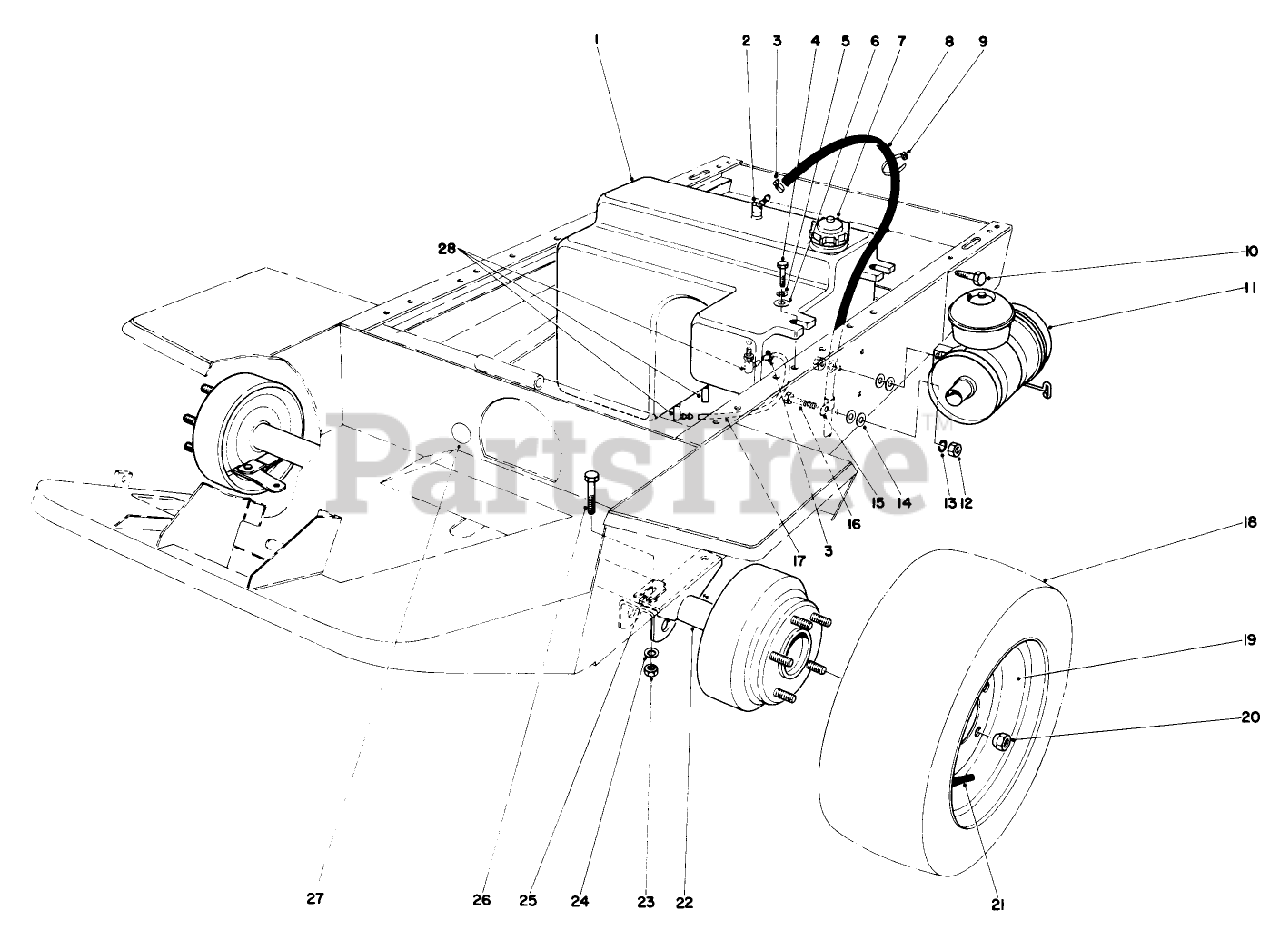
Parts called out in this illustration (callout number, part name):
1	GAS TANK
2	ELBOW
3	CLAMP-HOSE
4	SCREW-HH
5	WASHER-LOCK
6	Flatwasher
7	Gas Cap
8	GAS TANK VENT HOSE
9	Strap
10	SCREW-HH
11	AIR CLEANER ASM SERV
12	NUT-HEX
13	Lockwasher
14	WASHER-PLAIN
15	Clamp
16	SCREW-HH
17	HOSE-FUEL
18	20 X 8.00 - 10 TIRE
19	WHEEL ASM
20	NUT-WHEEL
21	VALVE STEM AND CAP ASM
23	NUT-HEX
24	WASHER-LOCK
25	SHIM-AXLE
26	SCREW-HH
27	OIL DECAL
28	FITTING-ELBOW, 90 DEG
